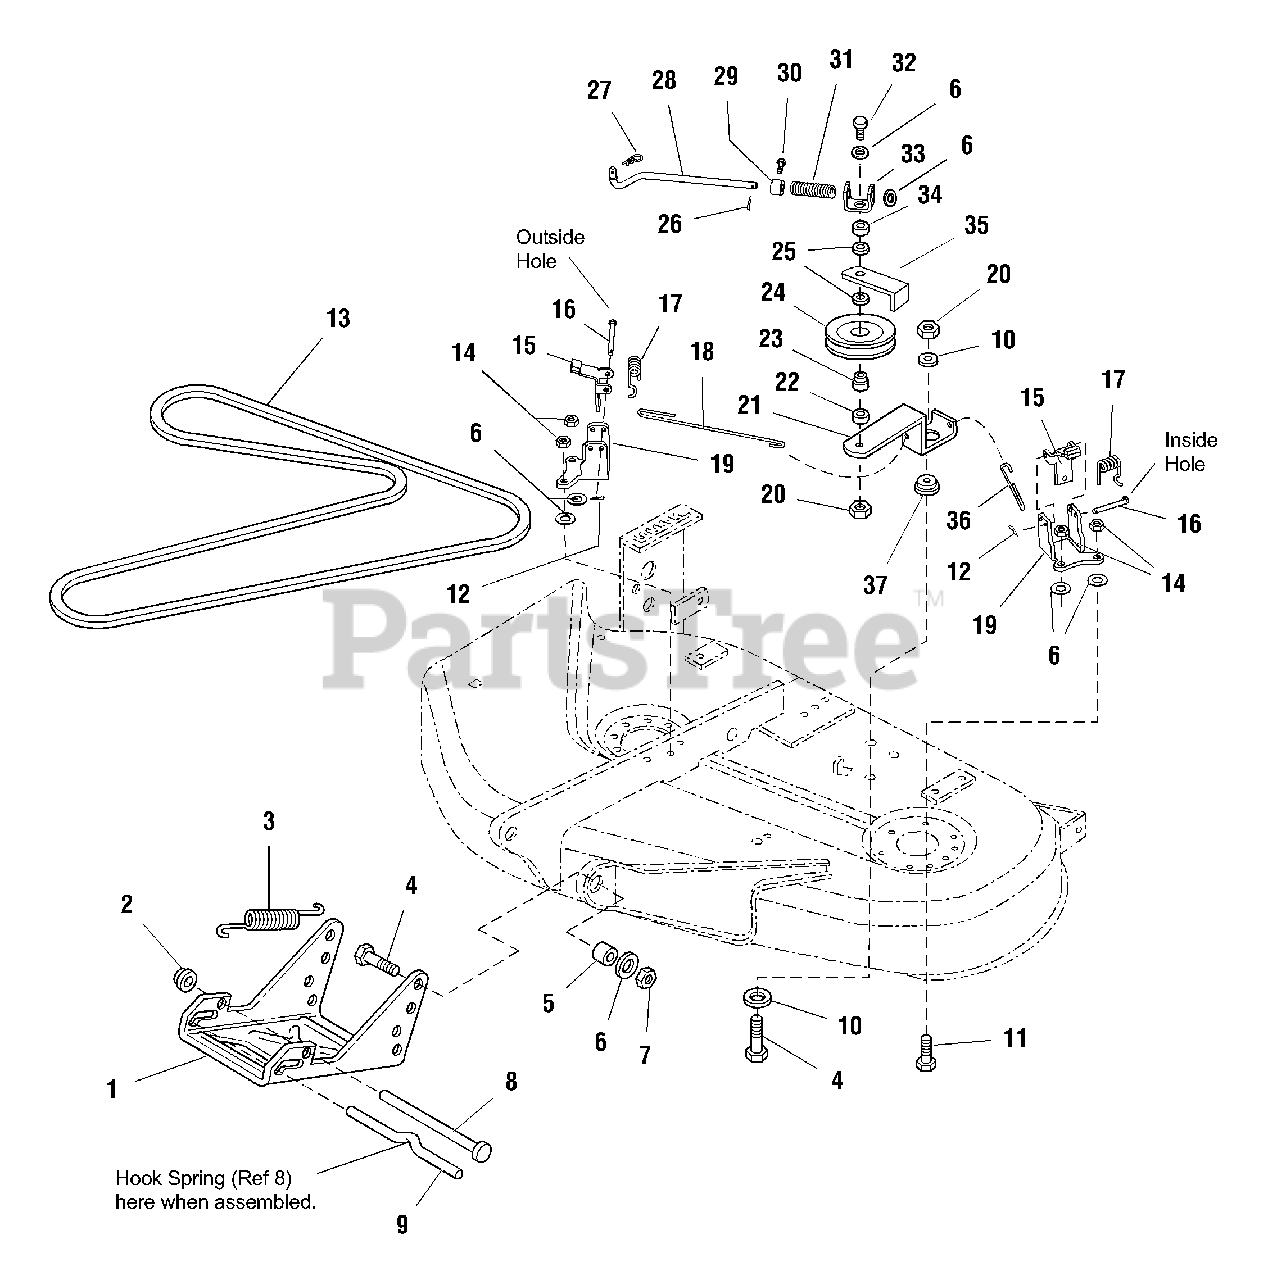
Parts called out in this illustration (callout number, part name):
2	NUT, Push, 1/2
3	SPRING, Gear Shift
4	CAPSCREW, Hex Hd, 3/8-16 x 1-1/2
6	WASHER, Plain, 3/8
7	NUT, ESNA Hex Lock, 3/8-16
8	ROD, Mower Hitch
10	WASHER , 3/8
11	CAPSCREW, Hex Hd, 3/8-16 x 1-1/4
12	PIN, Cotter, 3/32 x 3/4
14	NUT, Hex, Flange Whiz Lock, 5/16-18
15	BRAKE ACTUATOR & PAD ASSEMBLY
16	PIN, Clevis
17	SPRING, Torsion
18	ROD, R.H. Brake
19	SUPPORT, Brake
20	NUT, Hex Flange Whiz Lock, 3/8-16
21	ARM & GUSSET ASSEMBLY, Idler
24	PULLEY ASSEMBLY, with Bearing
25	WASHER, Plain, 3/8
26	COTTER PIN, 1/8 x 3/4
27	CLIP, Spring
28	ROD, Clutch
30	SET-SCREW, Hex Socket, Cup Pt, 5/16 - 18 x 1/2
31	SPRING, Compression
32	CAPSCREW, Hex Hd, 3/8-16 x 2-1/2
33	GUIDE, Clutch Rod
35	GUARD, Spring
36	ROD, L.H. Brake
37	SPACER, Idler Arm
